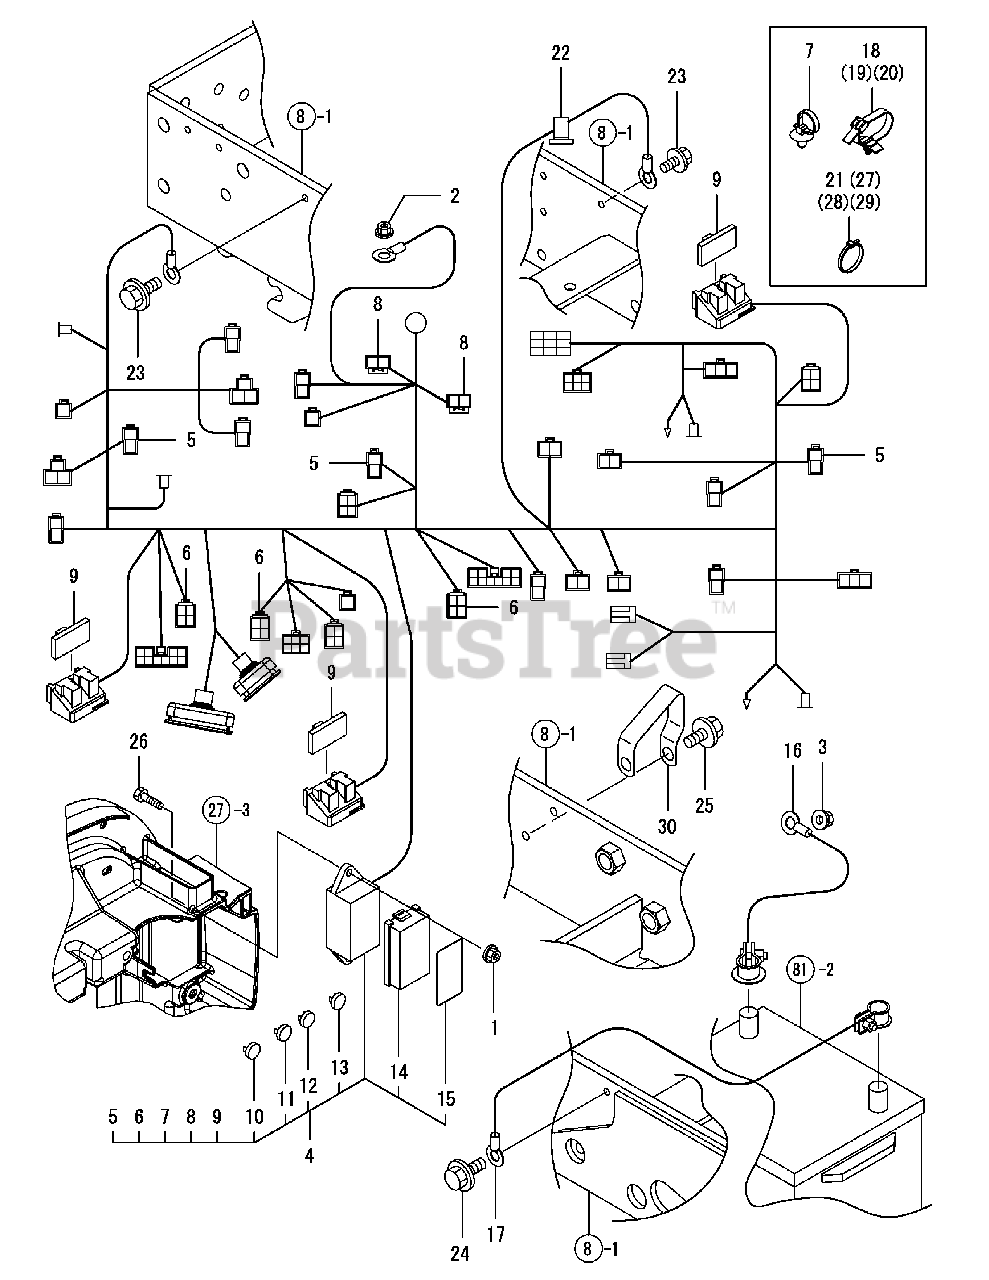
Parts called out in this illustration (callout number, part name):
1	NUT W/WASHER 6
2	NUT W/WASHER 6
3	NUT W/WASHER 8
4	HARNESS ASSY,WIRE
8	BLOW, SLOW FUSE 60A
14	COVER, FUSE BOX
16	CABLE, BATTERY
17	CABLE,BATTERY NEG.
22	STICKER 18,WIRE
23	BOLT M 8X 16 PLATED
24	BOLT M 8X 16 PLATED
25	BOLT M10X 20 PLATED
